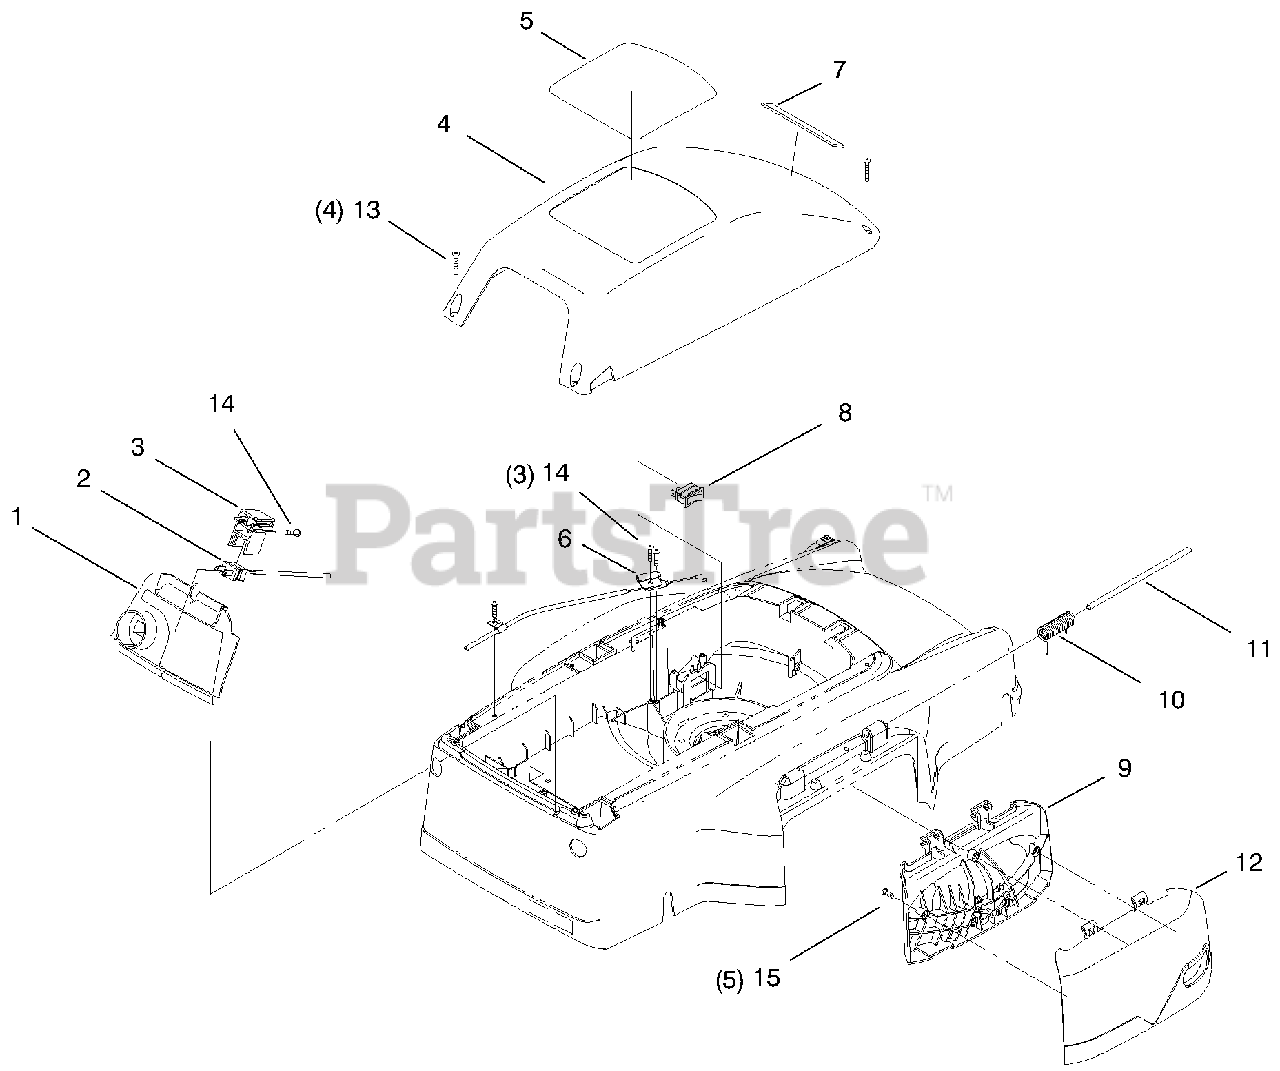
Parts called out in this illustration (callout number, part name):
1	ASM-Panel
2	Wire Harness
3	Housing-Plug
4	ASM-Cover
5	Decal-Cover
6	Bracket-Cable
7	Applique-Shroud
9	Mulch Plug-Inside
10	Spring-Torsion
11	Pin-Hinge
12	Mulch Plug-Outside
13	Screw-PPH
14	Screw-PH
15	Screw-PH
